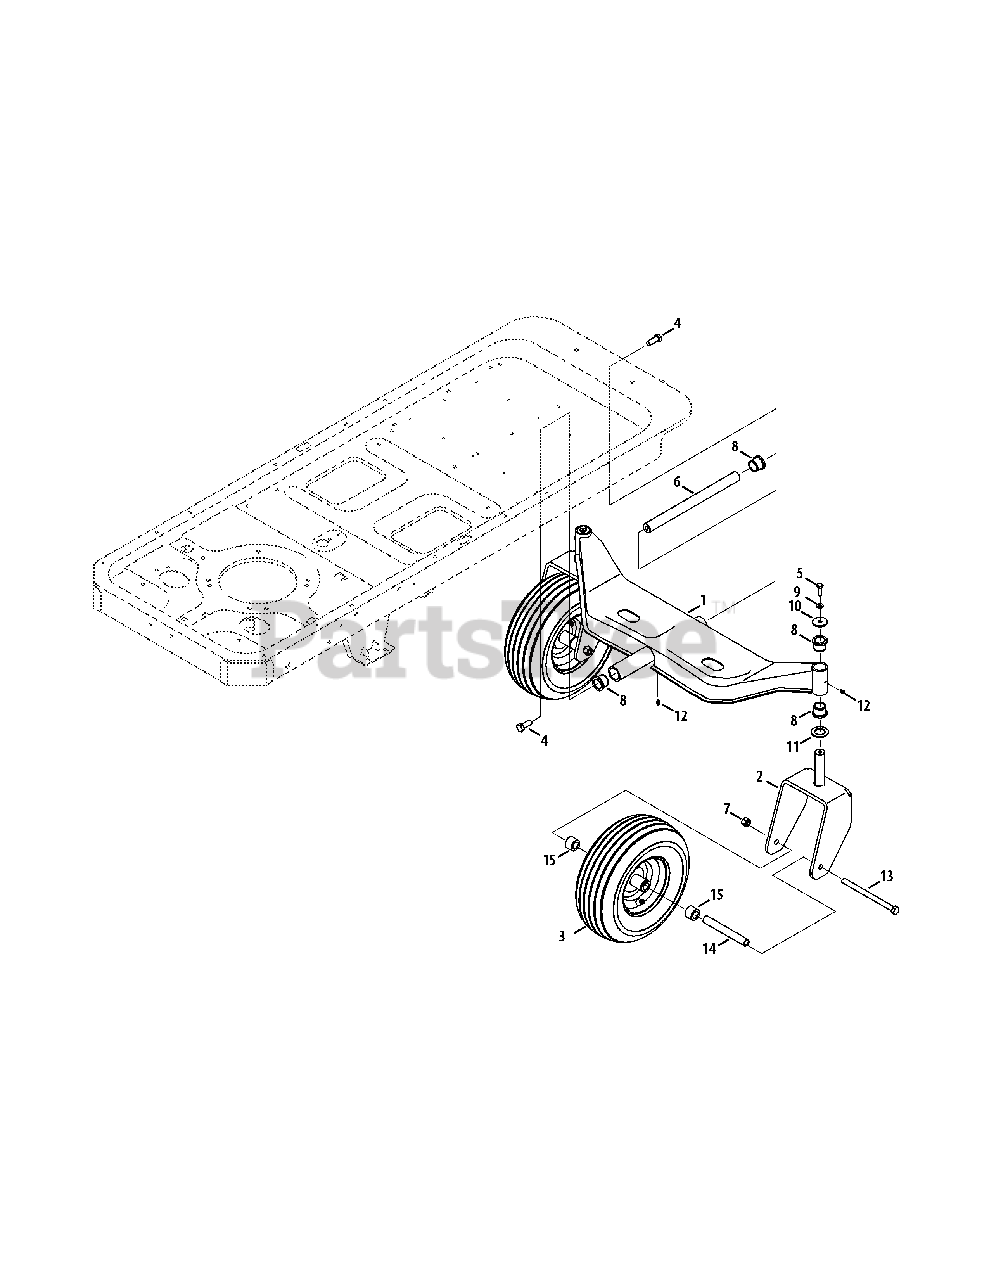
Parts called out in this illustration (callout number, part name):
1	Front Pivot Axle
2	Castor Wheel Bracket
3	Wheel Assembly, 13 x 5-6
4	Hex Lock Screw, 1/2-13 x 1.25
5	Hex Cap Screw, 3/8-16 x 1.0
6	Axle Shaft
7	Hex Lock Nut, 1/2-20
8	Flange Bearing, 1.0 x 1.246
9	Lock Washer, 3/8
10	Flat Washer, .39 x 1.5 x .134
11	Flat Washer, 1.0 x 1.75 x .107
12	Lube Fitting, 3/16
13	Bolt, 1/2-20 x 7.25
14	Spacer, .51ID x .75OD x 5.825
15	Hub, .76 x 1.23 x .92 Lg.
